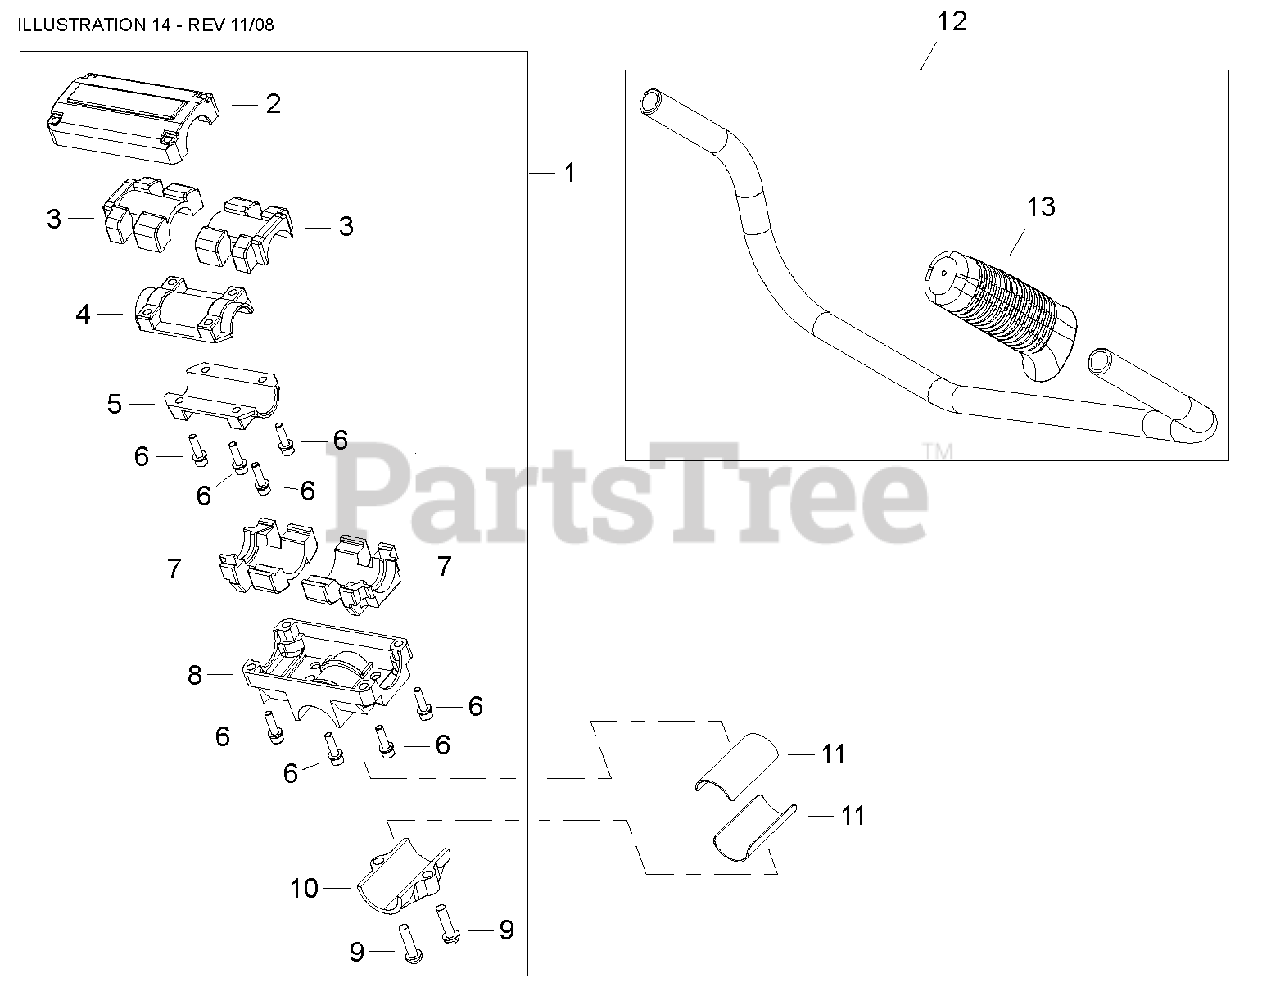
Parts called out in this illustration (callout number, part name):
1	HANDLE BRACKET KIT
2	BRACKET, HANDLE - UPPER
3	CUSHION - UPPER
4	CLAMP - UPPER
5	CLAMP - LOWER
6	SCREW - 5X25
7	CUSHION - LOWER
8	BRACKET, HANDLE - LOWER
9	SCREW - 6X25
10	BRACKET, HANDLE - UPPER
11	SPACER
12	HANDLE ASSY
13	GRIP
